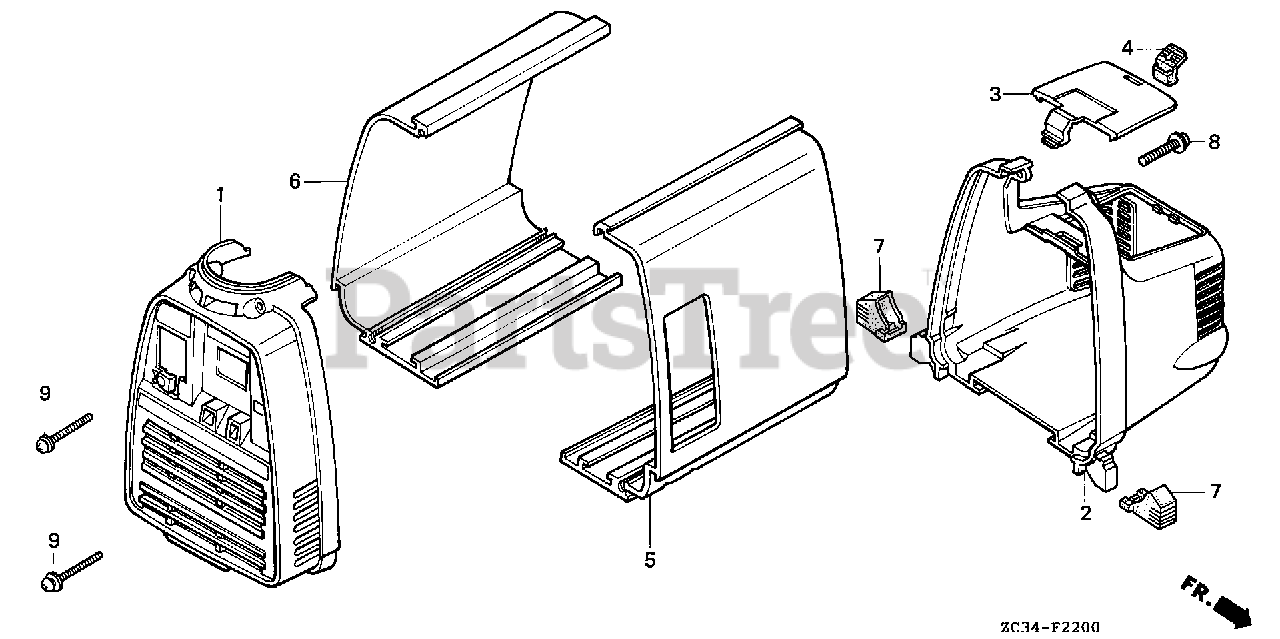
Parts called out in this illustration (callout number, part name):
1	COVER, FR.
2	PROTECTOR, RR.
3	COVER, PLUG
4	KNOB, PLUG COVER
5	FRAME, R. SIDE CENTER
6	FRAME, L. SIDE CENTER
7	RUBBER, SIDE (LOWER)
8	SCREW-WASHER (5X25)
9	SCREW-WASHER (5X35)
